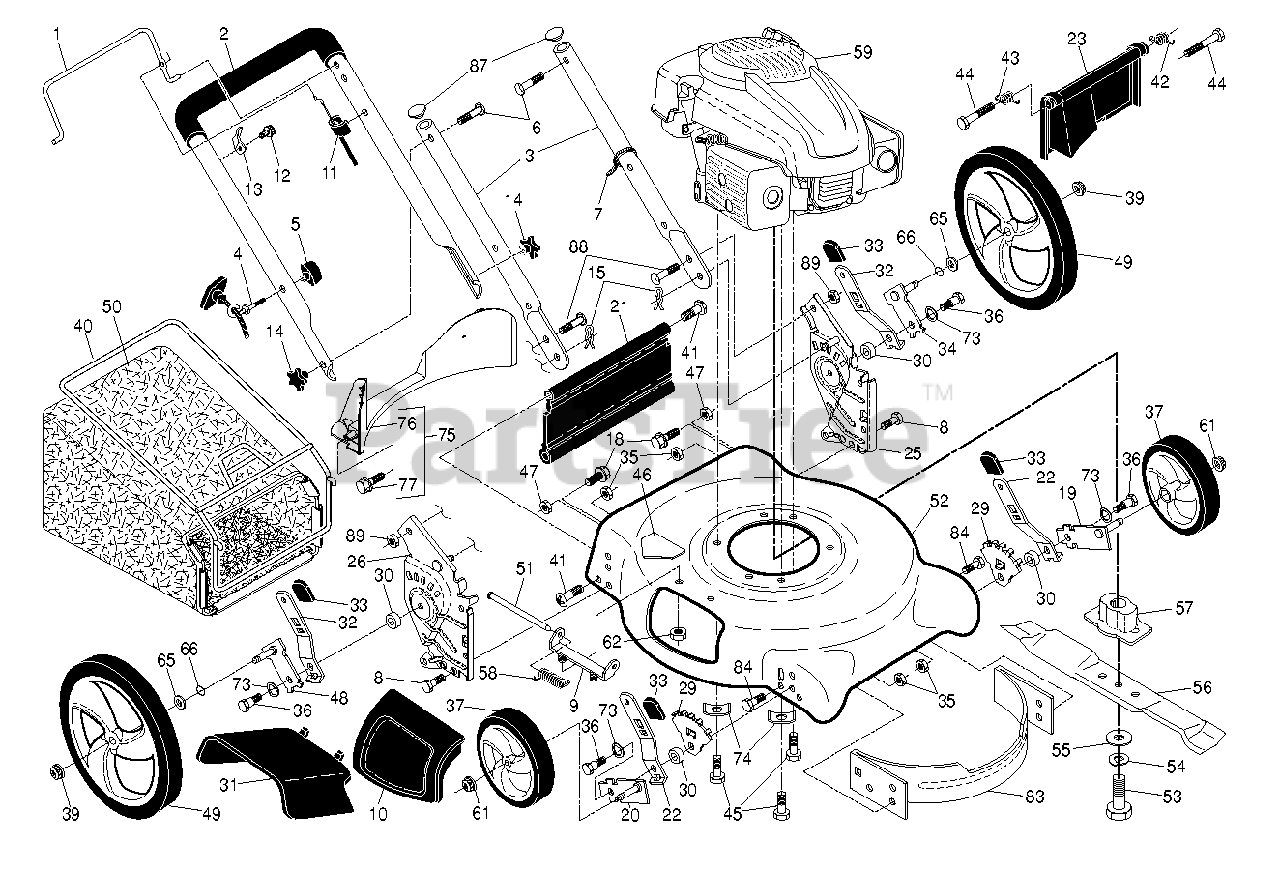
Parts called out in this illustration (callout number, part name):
1	BAIL.CONT.D.STRAIGHT.PUSH.BLK
2	HANDLE.UPPER.ECON.STRT.W/GRIP
3	HANDLE.LOWER.DOME.BT.BLACK
4	GUIDE.ROPE.BLK.ZINC.CHROM
5	T-KNOB.NEW ROPE GUIDE
6	BOLT, HANDLE 5/16-18X1.75
7	TIE GUIDE
8	BOLT
9	BRACKET.ASM.HOUSING.EZ.MUL
10	MULCH DOOR
11	CABLE.MZR.RATO.22"LOW.
13	BRACKET.UPSTOP.RT
14	KNOB.HANDLE.PLASTIC.STAR.BLACK
15	HAIRPIN COTTER
18	SCREW 1/4X20
21	KIT.SKIRT.21 DOMED.W/LIP
25	BRACKET.ASM.HANDLE.HW.21.LT.BL
26	BRACKET.ASM.HANDLE.HW.21.RT.BL
30	SPACER.HEIGHT.ADJUSTER
31	CLIP ON DISCHARGE GUARD
32	SPRING.SEL.22.ECON.HI-WHL.RATO
33	SELECTOR KNOB
35	NUT.FLANGE.HEX.5/16X18.BLACK
36	SHOULDER BOLT 5/16-18
37	WHEEL.8X1.75.MAG2.RAD3.GRAY
39	NUT.HEX.FLANGE.3/8-16.LOCKNUT
40	FRAME.BAG.21.REAR.DOMED.PUSH
41	SCREW.1/4-20X21/4.HEX.
42	SPRING.LH.22.REAR.DOOR.EZ.EMPT
43	SPRING.RH.22.REAR.DOOR.EZ.
45	BOLT 3/8-16X1-1/8
47	NUT.LOCK.5/16-18
49	WHEEL.12X1.75.MAG2.RAD3.GRY.TB
50	RB GBAG.24710010.BLK.GEN
51	ROD.HINGE.COMBI-C
52	HOUSING.21.MC.DOME.BLUE.TRI
53	SCREW, HEX HD 3/8-24 X 1-3/8
55	WASHER,HARDEN
56	BLADE.21.PUSH/RWGD/FWGD
57	ADAPTER.BLADE.W/KEY.25MM.CE
58	TORSION SPRING
61	NUT.HEX.FLANGE.3/8-16.LOCKNUT
62	LOCKNUT.NYLOC.1/4-20
65	WASHER PM
66	O-RING..070X.487.NEOPRENE
73	WASHER.CURVED.CYLINDRICAL
76	BAFFLE.REAR.PLASTIC.21.RD.ECON
77	SCREW.HX.13X.750
83	BAFFLE.FRONT.21.DOME.US
84	BOLT.5/16HEX.WHS.HD
87	PLUG.PLASTIC.7/8".14-20.GAUGE
89	LOCKNUT-FLANGE 5/16-18
